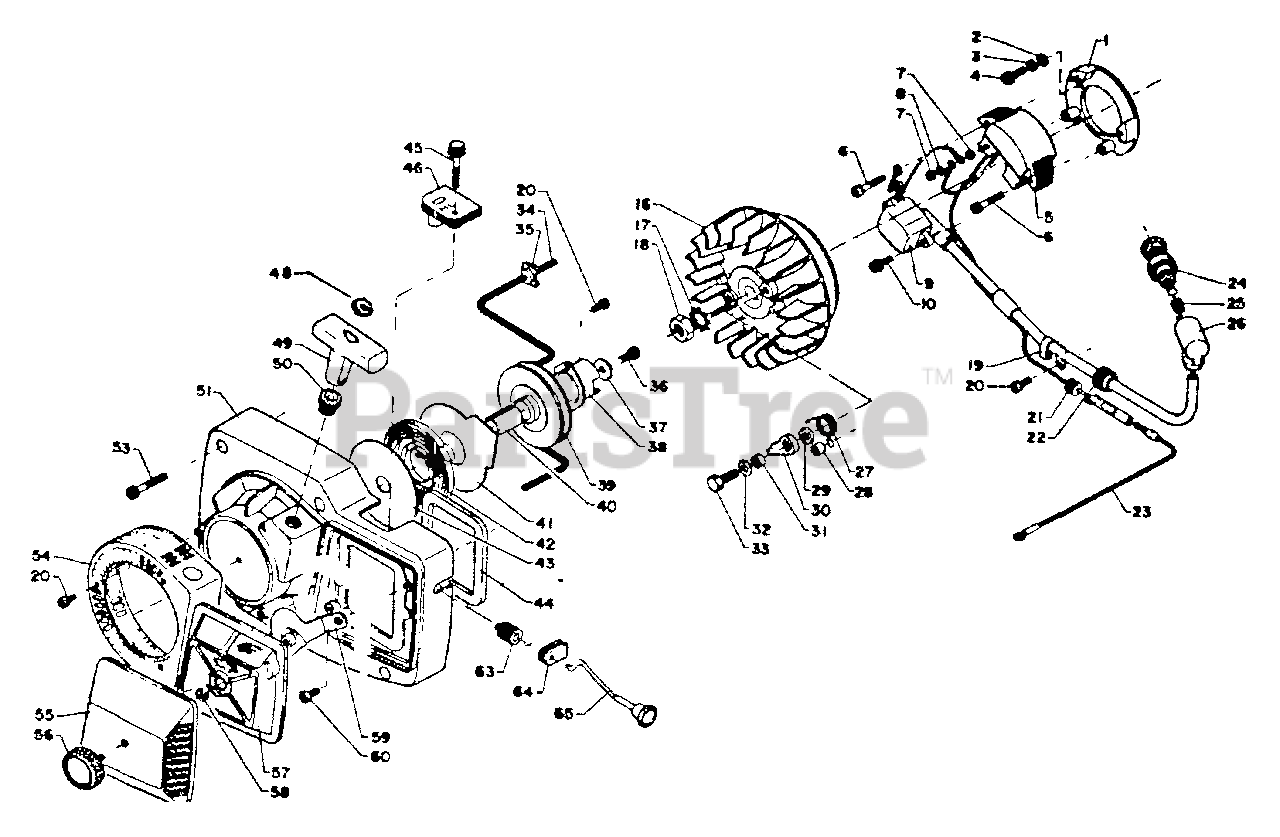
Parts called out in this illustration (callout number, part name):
1	PLATE, STATOR
2	WASHER - 5
3	LOCKWASHER - 5
4	SCREW - 5X15
5	COIL, IGNITION
6	SCREW - 4X25
8	LOCKWASHER - 3
9	COIL, IGNITION
10	SCREW - 4X14
16	FLYWHEEL
17	WASHER - 10
19	CLAMP
20	SCREW - 4X10
21	GROMMET
23	LEAD - GROUND
24	SPARK PLUG -- BPM-7A
25	TERMINAL, SPARK PLUG CAP
26	CAP, SPARK PLUG
27	SPRING, RETURN
30	PAWL, STARTER
32	WASHER - 6
33	BOLT - 6X16
34	ROPE, STARTER
35	RETAINER, ROPE
36	SCREW - 5X14
37	WASHER - 5
38	CATCHER, PAWL
39	REEL, ROPE
41	PLATE, STARTER
42	SPRING, REWIND
43	PLATE, STARTER
44	GASKET, INTAKE
45	SCREW, IDLE ADJUST
48	RING, RETAINING
49	GRIP, STARTER
50	GUIDE, ROPE
51	CASE, STARTER
53	SCREW - 5X30
54	FILTER, DEBRIS
55	COVER, AIR FILTER
56	THUMBSCREW
57	FILTER, AIR
58	RING, RETAINING - 4
59	BRACKET, AIR CLEANER
60	SCREW - 5X10
65	ROD, CHOKE
